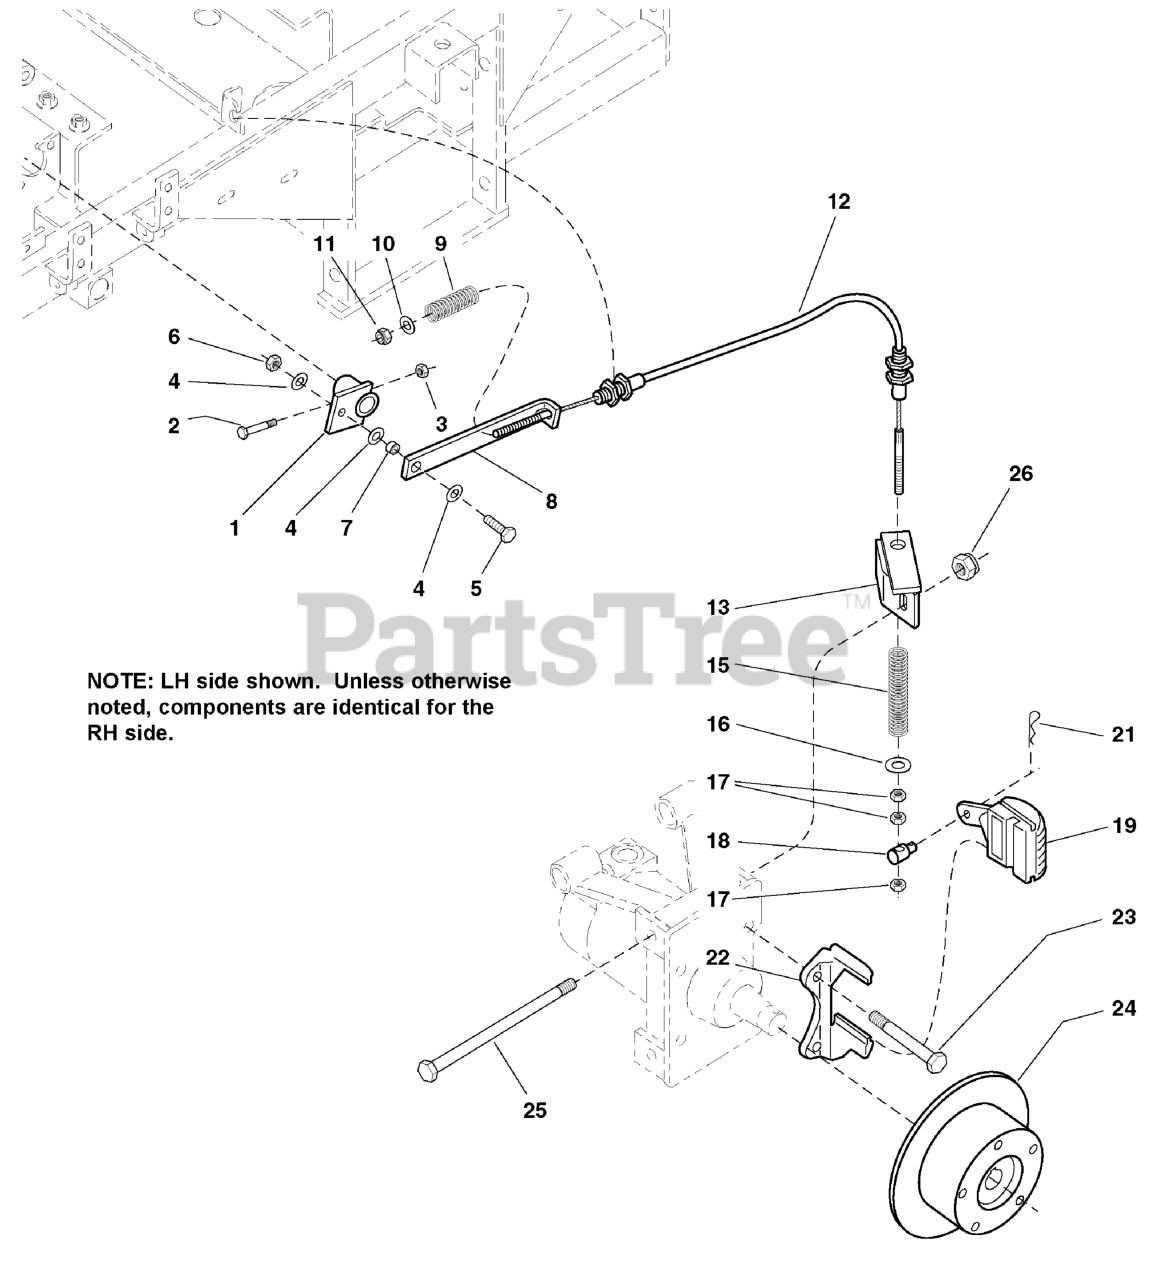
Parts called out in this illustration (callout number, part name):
1	PIVOT, LINKAGE MOUNT WELDMENT - BLK
2	BOLT, 1/4-20 x 1-3/4
3	NUT, 1/4-20 HEX NYLON LOCK
4	WASHER, 3/8 SAE
5	BOLT, 3/8-16 X 1-1/4" GD5 CZ
6	NUT, 3/8-16 HEX NYLON LOCK
7	SPACER, .38 x .50 x .27
8	LINK, Brake Lock
9	SPRING, Compression
10	WASHER, 5/16" SAE
11	NUT, 5/16-24 HEX NYLON LOCK
12	CABLE, Brake
13	BRACKET, Cable Mount-LH
15	SPRING, Compression
16	WASHER, 5/16" Fender
17	NUT, 5/16-24 Hex
18	ADJUSTER, Brake Linkage
19	BRAKE CALIPER, LH
21	HAIRPIN CLIP
22	MOUNT, Brake Caliper
23	BOLT, 1/2-20 x 3
24	HUB, 8" Brake Disc
25	BOLT, 1/2-13 x 7-1/2
26	NUT, 1/2-13 HEX NYLON LOCK
